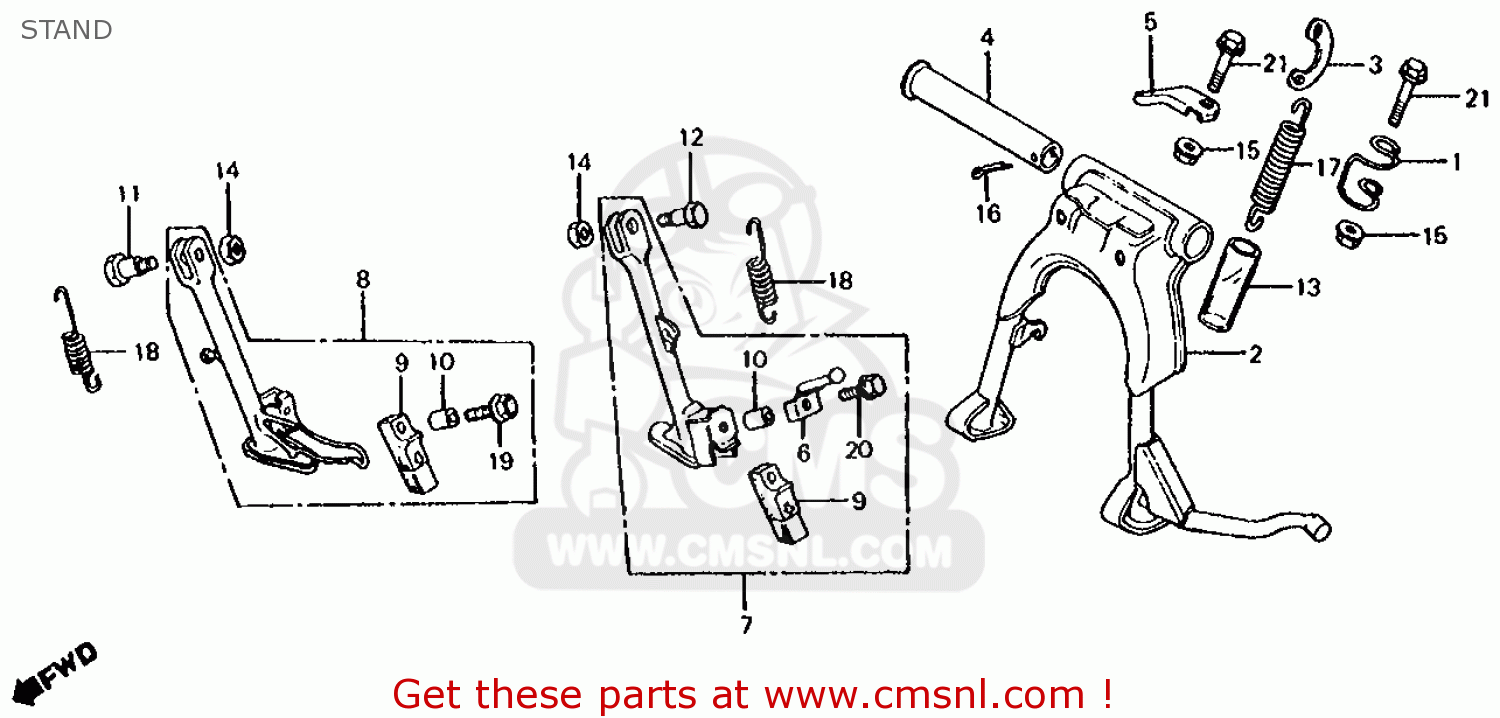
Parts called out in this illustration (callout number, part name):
1	CLIP, DRAIN TUBE
2	STAND COMP.,MAIN
3	PL,MAIN STAND SP
4	PIPE MAIN STAND
5	GUIDE,DRAIN TUBE
6	BAR COMP.,TREAD
7	SIDE STAND BAR
9	RUBBER,STAND
10	COLLAR,STAND
12	SCREW,PIVOT
13	COVER,STAND SPG.
14	NUT,HEX 10MM
16	PIN COTTER 2.5MM
17	SPRING.G,M.STAND
18	SPRING,D STAND
20	BOLT,FLANGE,6X28
21	BOLT,FLANG,8X40
